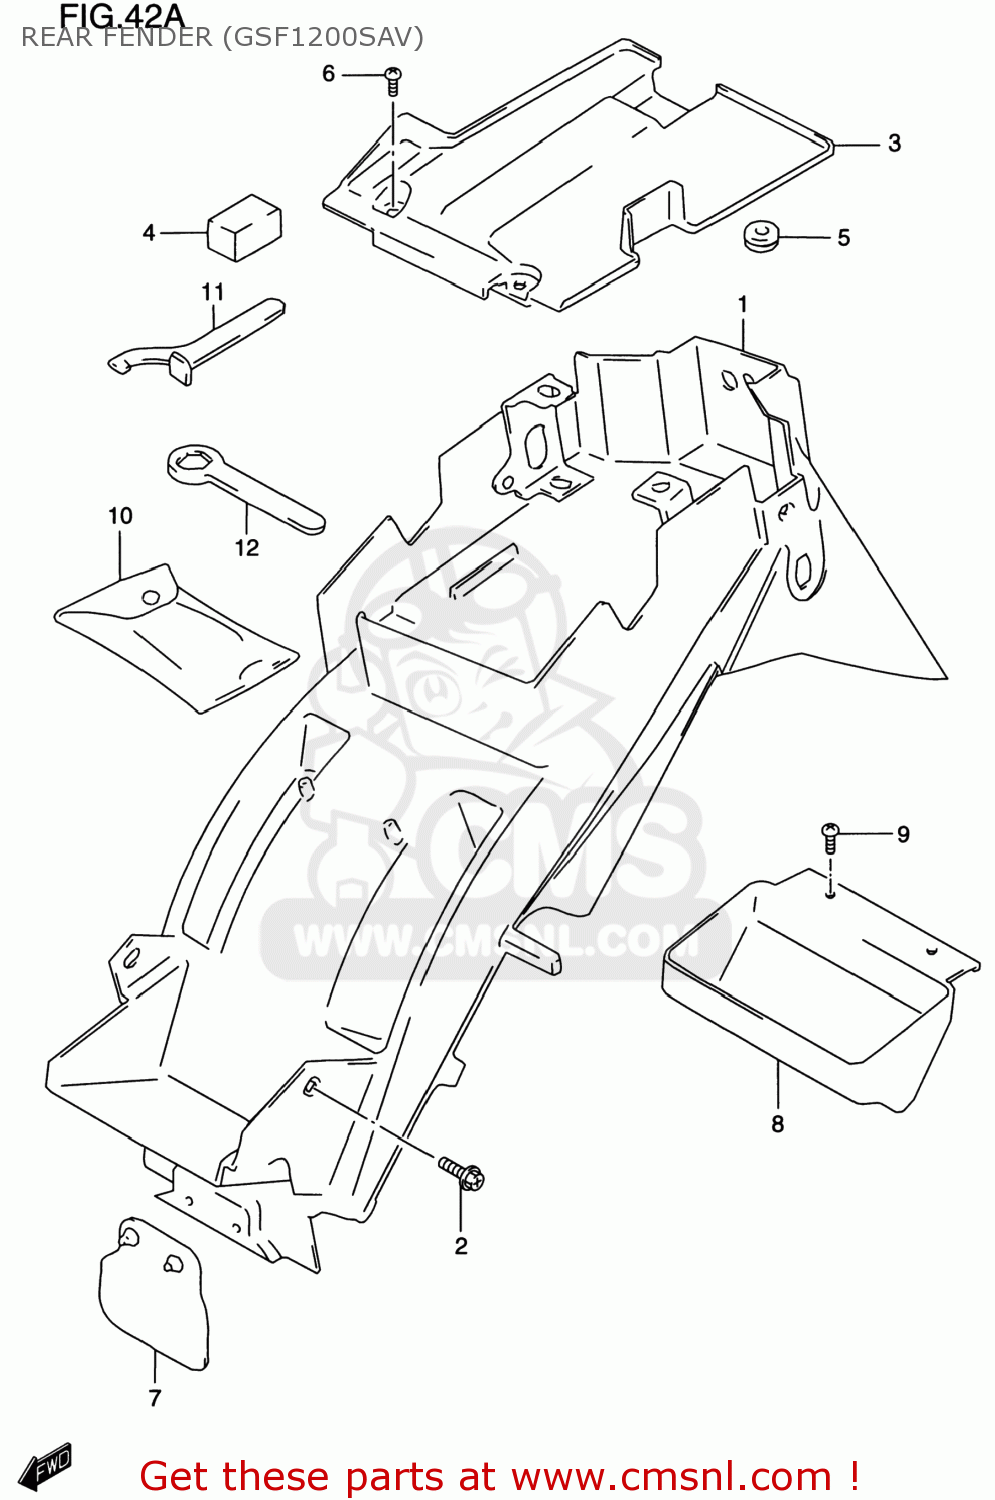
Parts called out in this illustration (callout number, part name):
1	FENDER COMP,REAR
2	BOLT
3	COVER,ECU
4	CUSHION,ECU COVER
5	CUSHION
6	SCREW
7	GUIDE,RR FENDER MUD
8	HOLDER,TOOL
9	SCREW
10	TOOL ASSY
11	CLAMP
12	RING,SPANNER(24)
